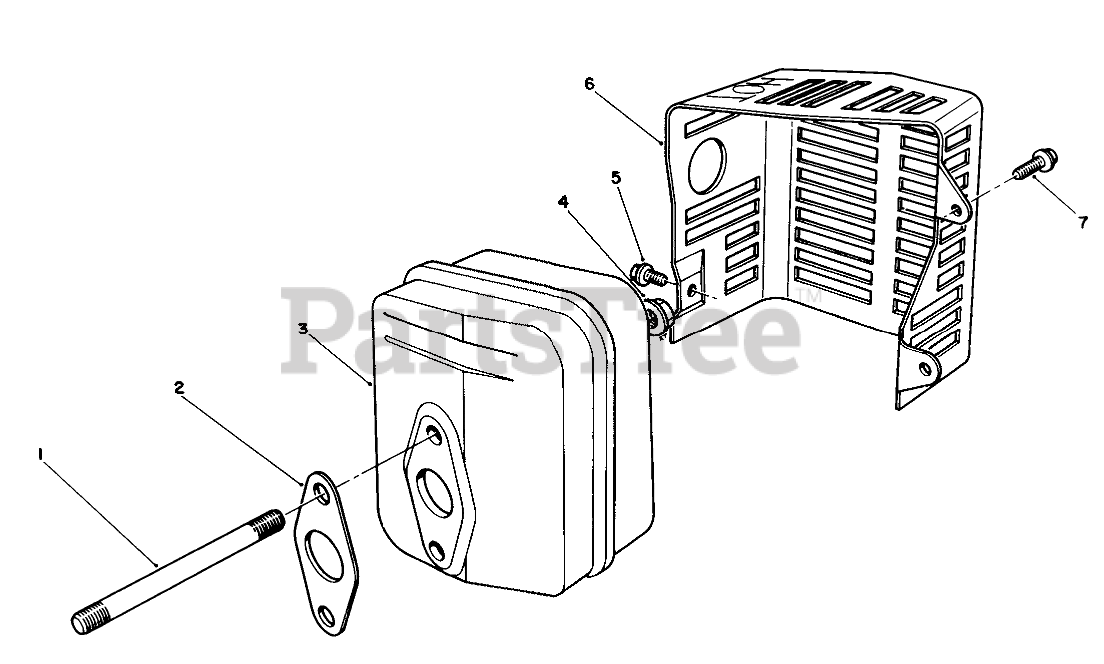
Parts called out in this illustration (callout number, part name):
2	GASKET
3	SHAFT
5	SCREW
6	COVER
